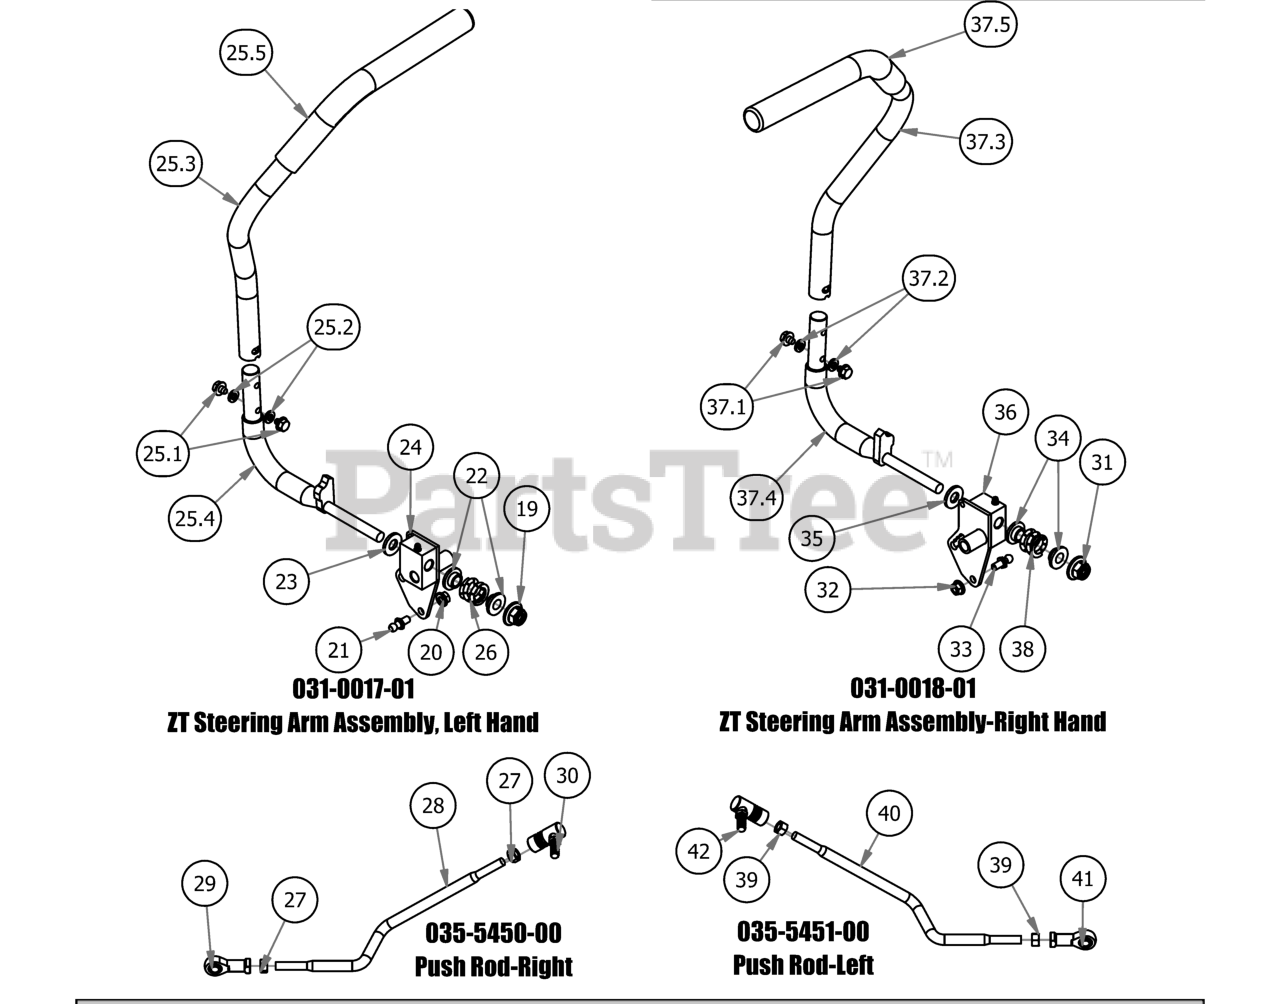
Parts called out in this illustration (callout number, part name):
19	1/2-13 Nylon Flange Nut
20	5/16" Flange Nut
21	10mm Damper Ball Stud-Steering
22	.515 ID Nylon Shoulder Washer
23	.505 Nylon Spacer
24	2017 Drive Lever Housing - Left
25	ZT Steering Arm-Left
25.1	5/16-18 1/2 HWH Bolt-Steering
25.2	5/16" Lock Washer
25.3	ZT Direction Steering Arm (Left)
25.4	Stering Arm Elbow (Left)
25.5	Rubber Grip
26	Drive Lever Spring
27	3/8" Fine Threaded Jam Nut
28	Push Rod - Right
29	Spherical Rod End - Outlaw
30	Quick Release Ball Joint
31	1/2-13 Nylon Flange Nut
32	5/16" Flange Nut
33	10mm Damper Ball Stud-Steering
34	.515 ID Nylon Shoulder Washer
35	.505 Nylon Spacer
36	2017 Drive Lever Housing - Right
37	ZT Steering Arm-Right
37.1	5/16-18 1/2 HWH Bolt-Steering
37.2	5/16" Lock Washer
37.3	ZT Direction Steering Arm (Right)
37.4	Stering Arm Elbow (Right)
37.5	Rubber Grip
38	Drive Lever Spring
39	3/8" Fine Threaded Jam Nut
40	Push Rod - Left
41	Spherical Rod End - Outlaw
42	Quick Release Ball Joint
